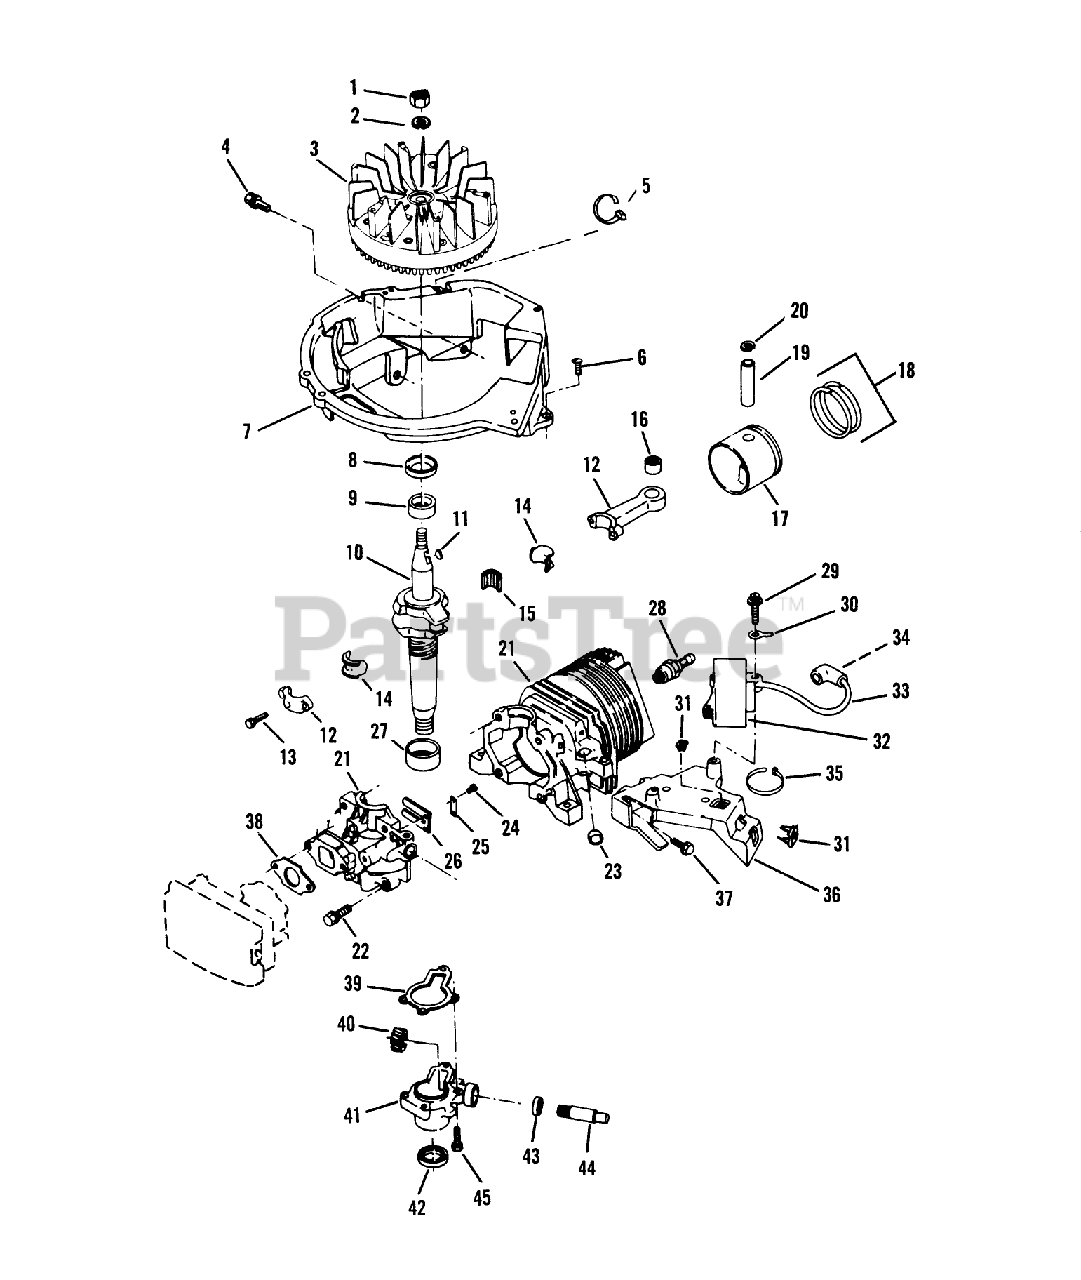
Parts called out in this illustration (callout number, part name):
1	NUT
4	SCREW-SEMS
6	SCREW F
8	SEAL-OIL
9	BEARING V
11	KEY
13	SCREW-HSH
14	LINER ASM
15	BEARING-NEEDLE
16	BEARING AY F
20	RING-RETAINING
22	SCREW S
23	PLUG-CORE VF
24	SCREW-HH
25	PLATE-BACKUP, REED
27	BEARING S
30	TERMINAL S
31	NUT-CLIP
33	HT LEAD&COVER XEV
36	C.D. BRKT F
38	GASKET CARB S
39	GASKET S
42	SEAL-OIL
43	SEAL S
44	DR SHAFT,PTO S
